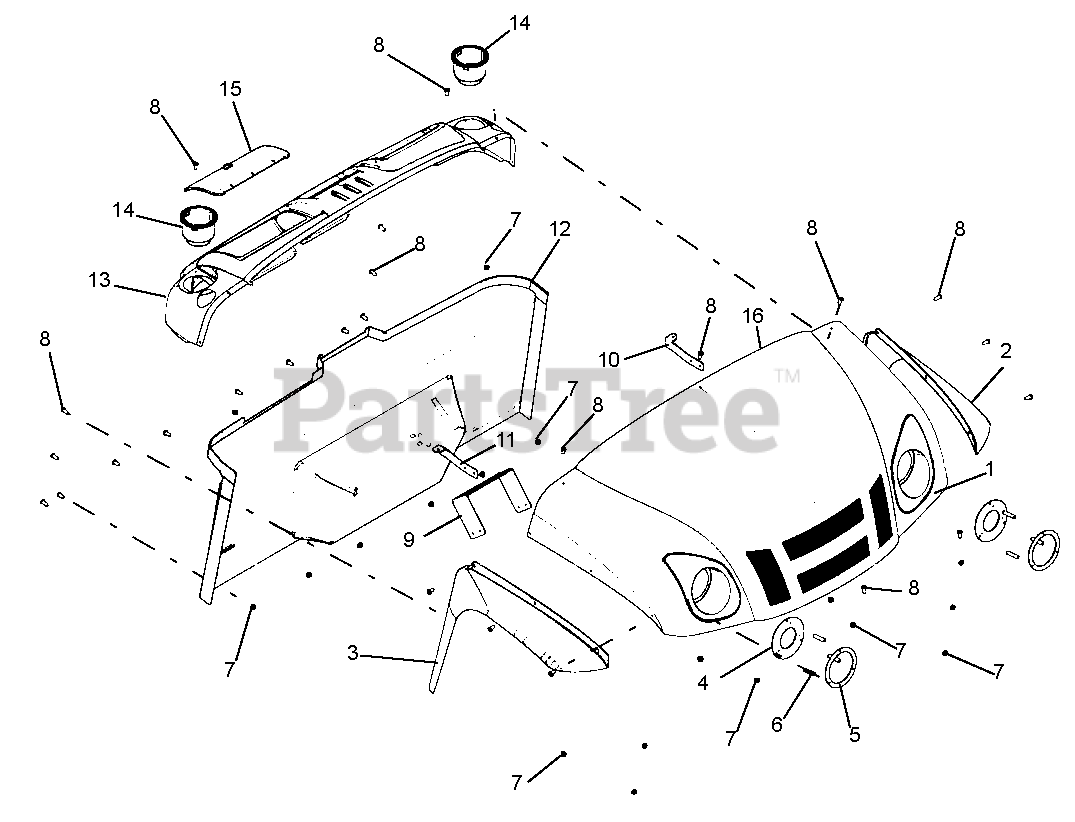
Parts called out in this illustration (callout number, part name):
1	KIT, HOOD WITH DECALS (996123, 125, 146)
2	FENDER, FRONT, LEFT HAND
3	FENDER, FRONT, RIGHT HAND
4	TOP FLANGE, HEADLIGHT
5	BASE FLANGE, HEADLIGHT
6	SPACER, HEADLIGHT
7	NUT, HEX FLANGE TL 1/4-20 ZNYCR
8	TTHMS 1/4-20 X 1 ZNYCR
9	BRACKET, MOUNTING SWITCH
10	BRACKET, CUPHOLDER, LEFT HAND
11	BRACKET, CUPHOLDER, RIGHT HAND
12	KIT, FOOTWELL WITH DECALS
13	DASH ASSEMBLY WITH DECALS
14	CUP, HOLDER SNAP-IN 3.75 OD
15	DOOR, GLOVEBOX ASSEMBLY
16	TRIM, 1/8 RUBBER EDGE
